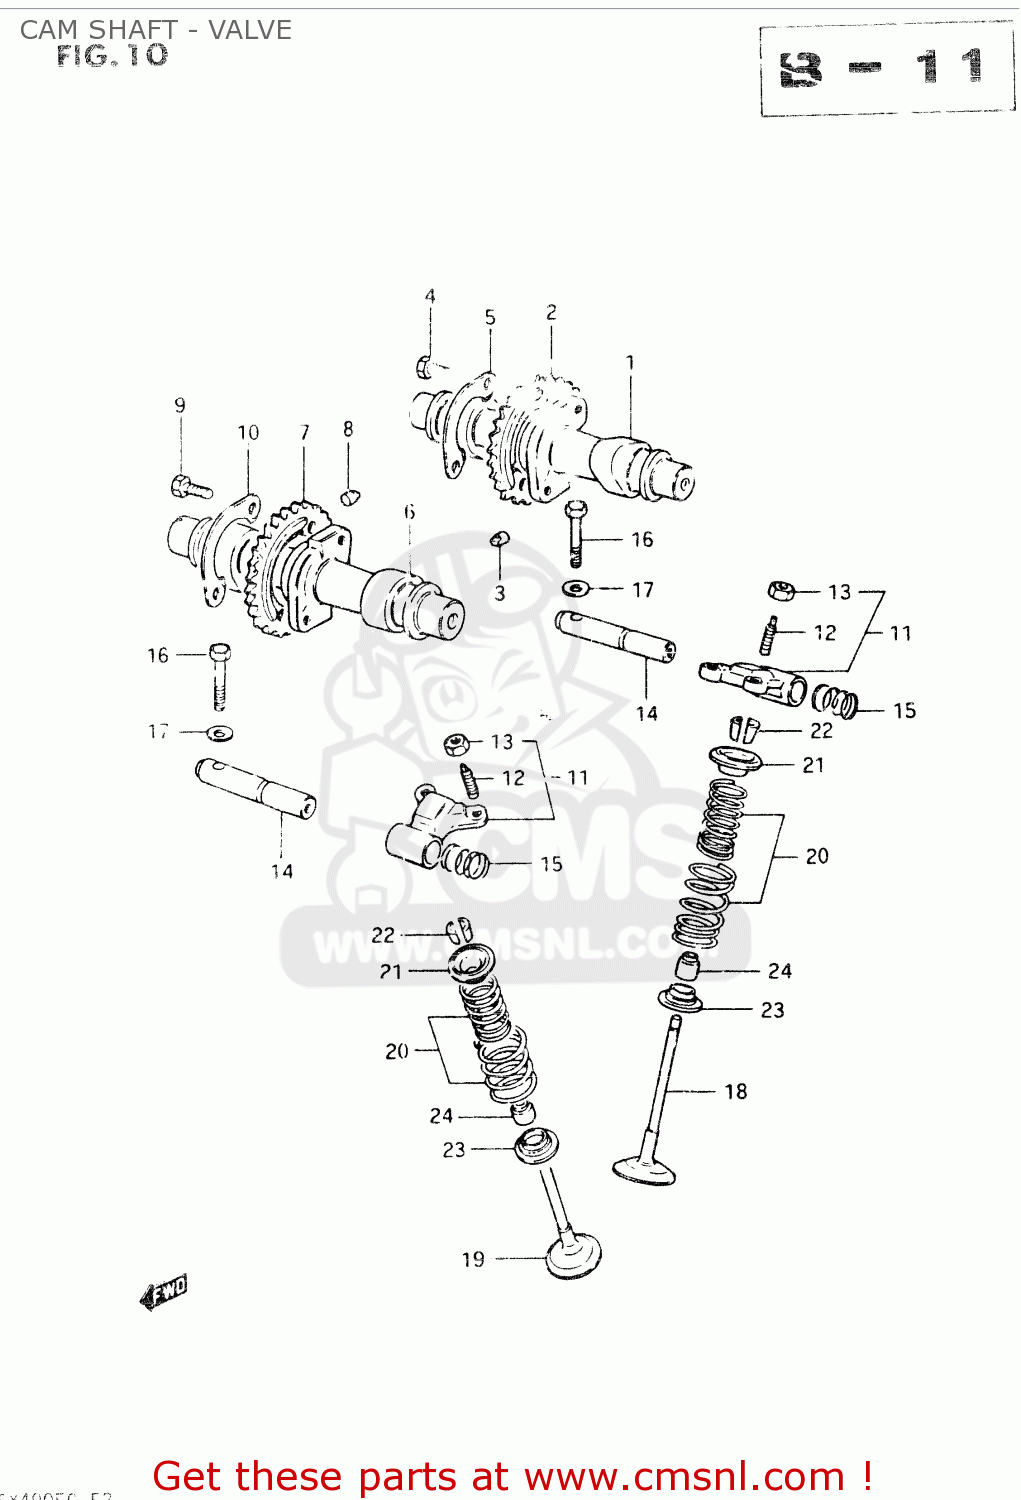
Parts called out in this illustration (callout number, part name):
1	CAM SHAFT, INTAKE
2	SPROCKET (NT:30)
3	PIN,SPROCKET
4	BOLT(6X12.5)
5	WASHER,CAM CHAIN SPROCKET
6	CAMSHAFT,EXHAUST
7	SPROCKET (NT:30)
8	PIN,SPROCKET
9	BOLT(6X12.5)
10	WASHER,CAM CHAIN SPROCKET
11	ARM,VALVE ROCKER
12	SCREW,TAPPET ADJUSTING
13	NUT,ADJUSTING
14	SHAFT,VALVE ROCKER ARM
15	SPRING
16	BOLT
17	WASHER, LOWER
18	VALVE,INTAKE
19	VALVE,EXHAUST
20	SPRING SET,VALVE
21	RETAINER,VALVE SPRING
22	COTTER VALVE
23	SEAT,VALVE SPRING
24	OIL SEAL
